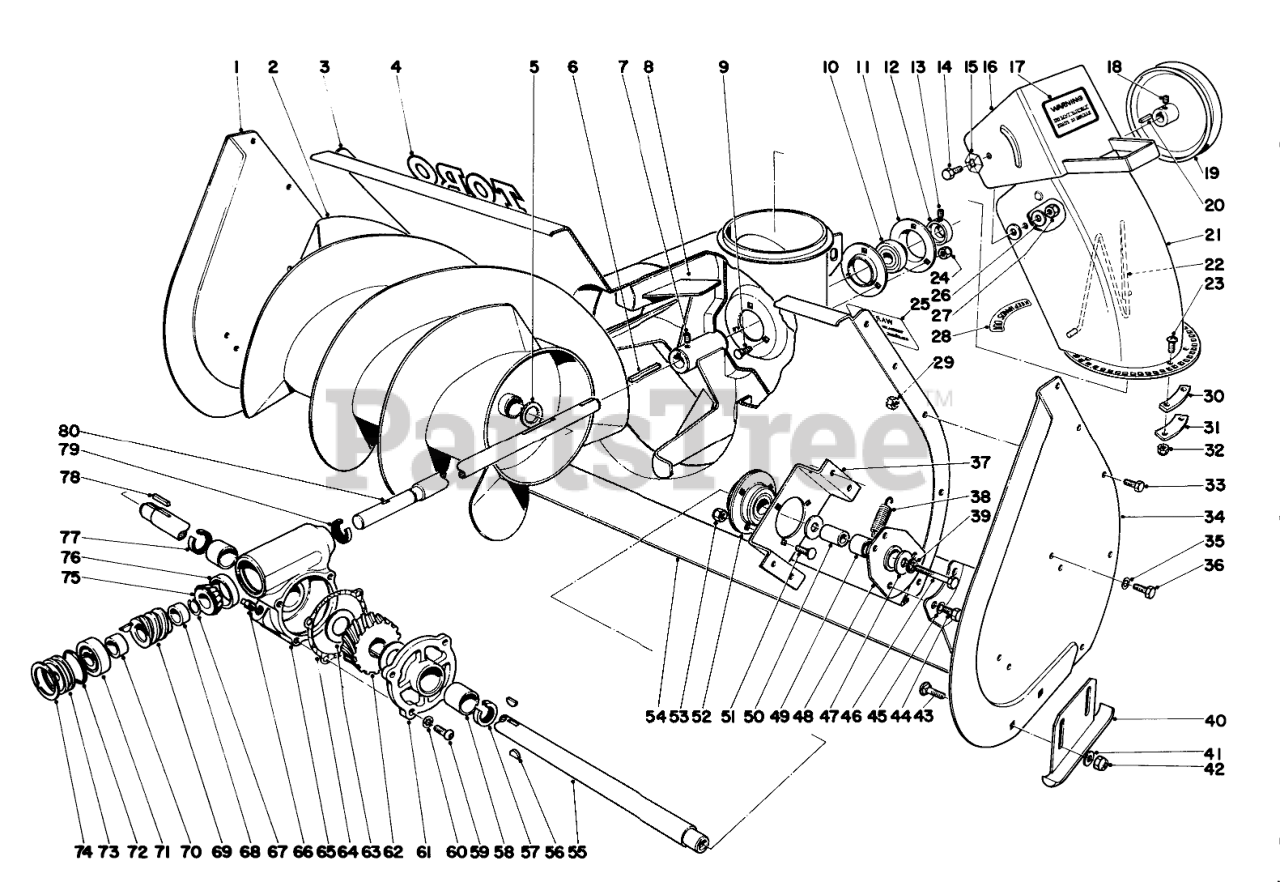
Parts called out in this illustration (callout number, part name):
1	Side Plate Auger
2	Auger (R.H.)
3	Auger Housing
4	Decal-Toro 732
5	Spacer Auger Shaft
7	SCREW-HSH
8	Impeller
9	BOLT-CARR
10	BALL BRG W/COLLAR
11	BRG FLANGE
12	EXT LOCKING COLLAR
13	SCREW-HSH
14	SCREW-HH
15	LOCKWASHER-PYRAMID
16	Deflector
17	Decal-Chute Warning
18	SCREW-HSH
19	1/2 X 9.5 DIA PULLEY
20	SQUARE KEY
21	Upper Chute
22	Chute Wire
23	SCREW-HSBH
24	NUT-LOCK, NI
25	Decal-Auger Warning
26	WASHER-FLAT
27	NUT-LOCK, NI
28	Decal
29	NUT-LOCK, NI
30	CHUTE TAB SPACER
31	UPPER CHUTE TAB
32	NUT-LOCK, NI
33	SCREW-HH
34	Side Plate Auger
35	WASHER-LOCK
36	SCREW-HH
37	Auger Bearing Bracket
38	SPRING-TENSION
39	WASHER-LOCK
40	Skid
41	WASHER-FLAT
42	NUT-LOCK, NI
43	BOLT-CARR
44	SCREW-HH
45	WASHER-LOCK
46	SCREW-HH
47	Washer Auger Shaft
48	Scraper Blade-Mount Ass-y. (Incl. Ref. #49)
49	7/8 ID X 1.128 X 7/8 LG BSHG
50	Spacer Auger End
51	BOLT-CARR
52	Bearing Flange
53	NUT-LOCK, NI
54	Blade-Scraper
55	Shaft Auger
56	KEY-WOODRUFF
57	SEAL-OIL
58	Bushing
59	SCREW-HSBH
60	WASHER-LOCK
61	Gear Box Cover (Include Ref. #57 & 58)
62	GEAR-WORM, 27T
63	WASHER-THRUST
64	Gasket
65	Gear Box Auger
66	PLUG-PIPE, SQH
67	RETAINER RING
68	WORM SHF REAR SPACER
70	Spacer-Worm Shaft Front
71	.750 BALL BEARING
72	O-RING
74	INTRNL RETAINING RING
75	3/4 ROLLER BRG CONE
76	1.750 ROLLER BRG CUP
77	SEAL-OIL
79	SEAL-OIL
80	Shaft Worm
